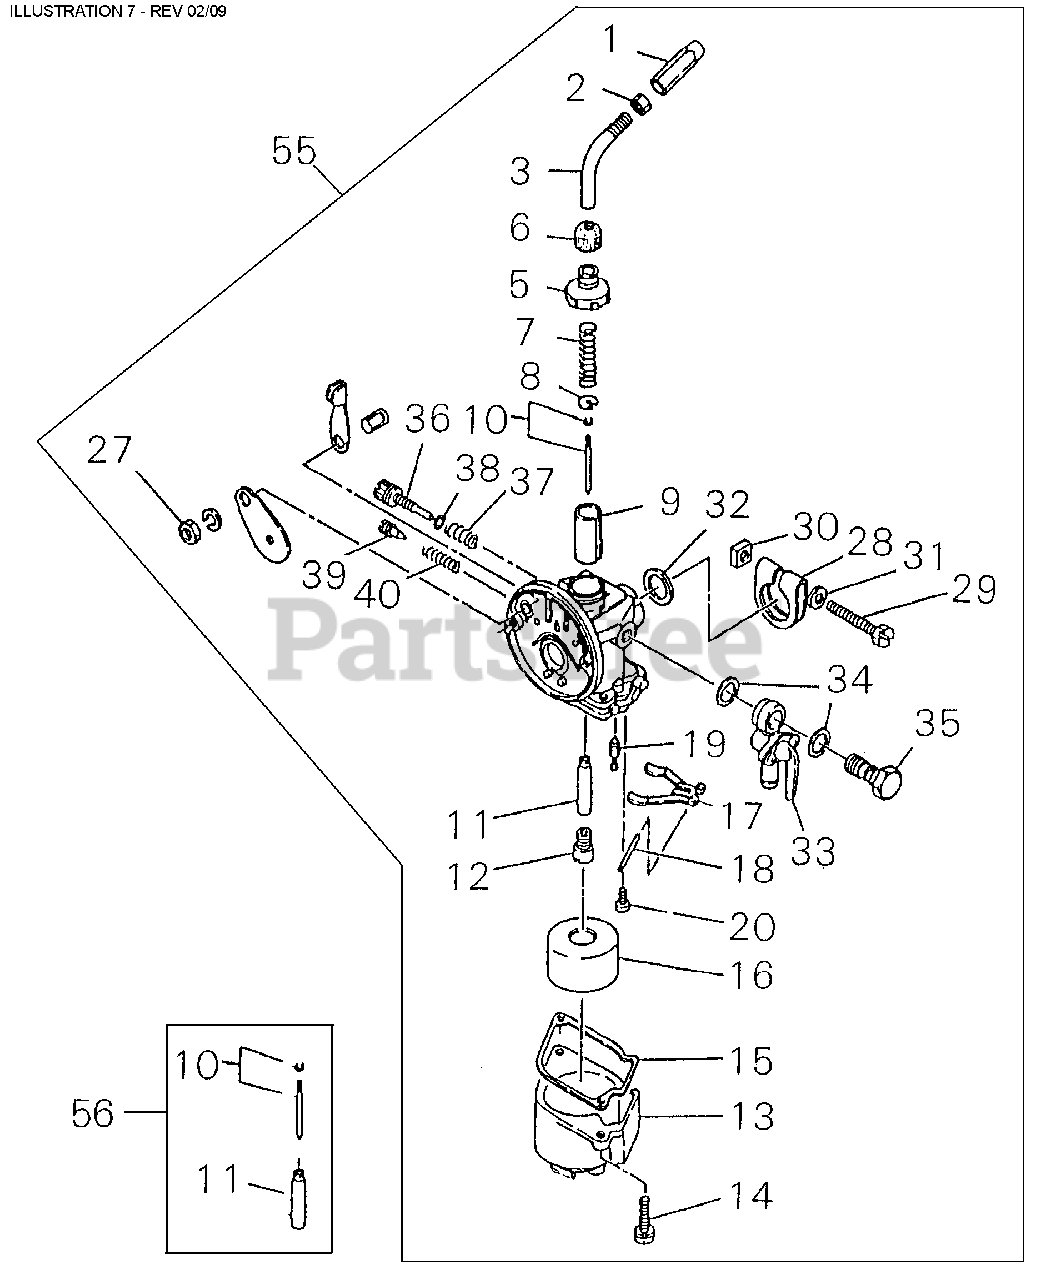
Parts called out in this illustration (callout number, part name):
1	ADJUSTER, CABLE
2	NUT, LOCK
3	PIPE, CABLE ADJUSTER(4 pieces ×2 M)
5	CAP, CARBURETOR
6	CAP, DUST
7	SPRING, THROTTLE
8	WASHER, SPRING SUPPORT
9	VALVE, THROTTLE
10	NEEDLE, JET
11	NOZZLE
12	JET, MAIN
13	CHAMBER, FLOAT
15	GASKET, FLOAT CHAMBER
16	FLOAT
17	HINGE, FLOAT
18	PIN, HINGE
19	VALVE, INLET NEEDLE
20	SCREW
27	NUT, LOCK
28	CLAMP
29	BOLT
31	WASHER
32	GASKET, MOUNTING
33	COCK, FUEL
34	GASKET
35	BOLT, BANJO
36	SCREW, SLOW STOP
37	SPRING
38	O-RING
39	SCREW, SLOW AIR
40	SPRING
55	CARBURETOR
56	NEEDLE KIT, JET
